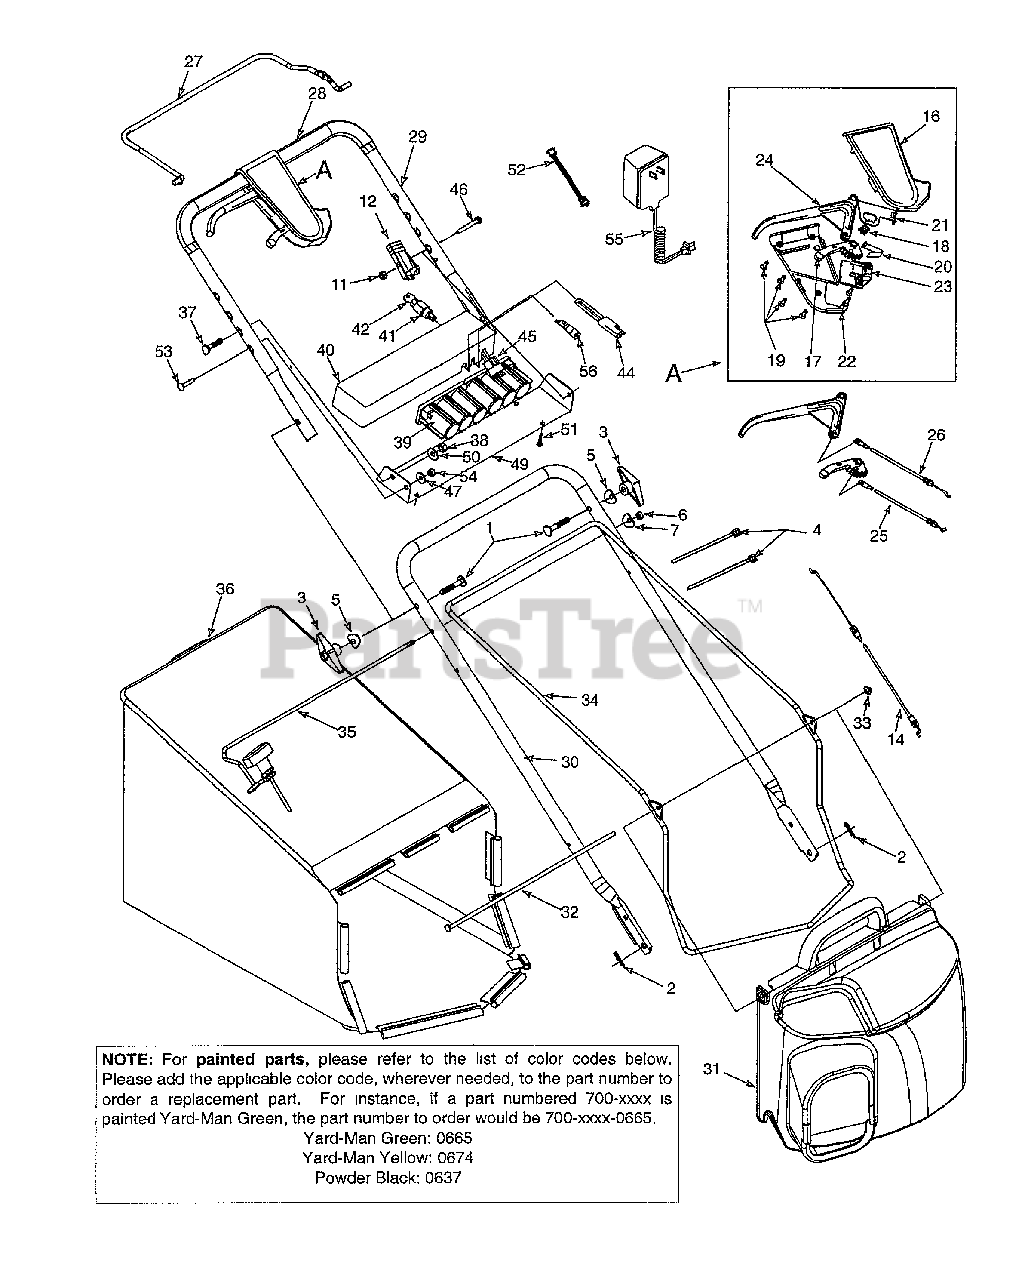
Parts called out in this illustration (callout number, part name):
1	Bolt Cur. Carr. 5/16-18 x 2.0
2	Cotter Pin .072 x 1.12 Lg.
3	Knob Assembly 5/16-18
4	Strap 4.3" Lg.
5	Wash. Sad. .320 ID x.830 OD
6	Handle Knob 1/4-20
7	Saddle Washer
11	Nut 1/4-20 Top Lock Nut Insert
12	Control Cable Housing
14	Control Cable 46" Lg.
16	Upper Control Housing
17	6-Speed Shift Lever
18	Gear Insert
19	C Sunk Tap Screw #10-16x.625
20	Shift Lever Spring
21	6 Spd. Rack Cable Brkt.
22	Lower Control Housing
23	Cable Mounting Cap
24	Control Lever
25	6 Spd. Cable
26	Self Prop. Cable, Orange 51"
28	Foam Grip
31	Grassbag Cover w/ logo
32	Pivot Rod
33	Cap Nut
36	Grassbag
37	Cur. Carr. Bolt 5/16-18 x 1" Lg.
38	Hex Nut 5/16-18 Thd.
39	Battery Pack - 12 Volt
40	Battery Tray
41	Ignition Switch
42	Ignition Key
44	Plug
45	Wire Harness
46	Hex Bolt 1/4-20 x 1.3" Lg.
47	Bell Wash 1/4" I.D.
51	Truss Mch. Tap Scr. 1"
52	Harness Ext.
53	Scr. 1/4-20 x 1.25
54	Hex Nut 1/4-20
55	Battery Charger
56	Fuse Holder
